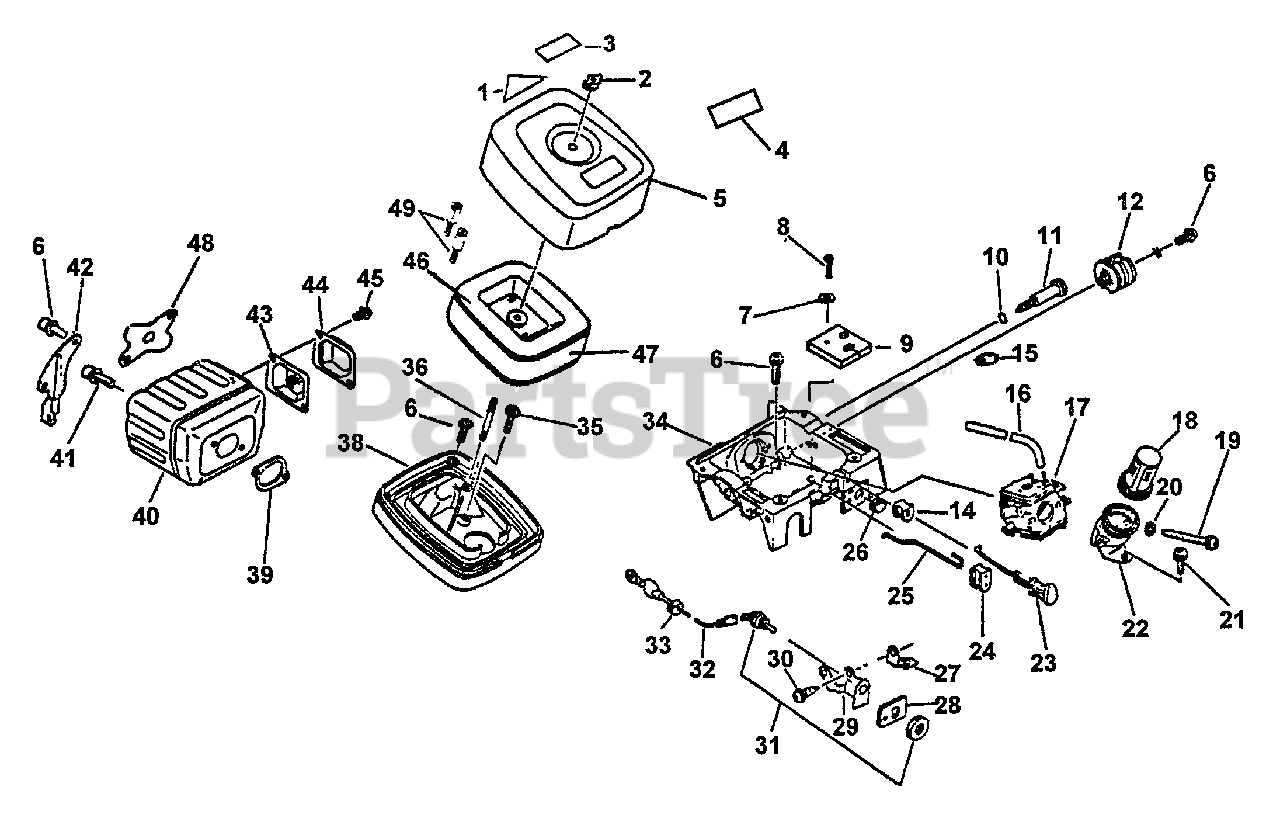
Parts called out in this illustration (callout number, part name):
2	NUT
3	LABEL, CAUTION
4	LABEL, MODEL
5	COVER, AIR FILTER
6	BOLT 5×14
8	PIN, COTTER 3×18
9	PAD, FOAM
10	O-RING 7
11	SCREW, IDLE ADJUST - GRAY
14	GROMMET
16	PIPE, IMPULSE
17	CARBURETOR - HDA-85
18	SCREEN, FILTER
19	SCREW 5×53
20	WASHER, FLAT 5.5×10×0.8
21	SCREW 5×14
23	ROD, CHOKE
24	GROMMET, THROTTLE ROD
25	ROD, THROTTLE
27	PLATE, GROUND
28	LABEL - SWITCH
29	BRACKET, SWITCH
30	SCREW 5×10
31	SWITCH, ON-OFF
32	LEAD - GROUND
34	CASE, CARBURETOR
35	BOLT 5×25
38	CASE, AIR FILTER
39	GASKET, EXHAUST
40	MUFFLER
41	BOLT 5×20
42	BRACKET, MUFFLER
43	SCREEN, SPARK ARRESTER
44	COVER, MUFFLER
45	BOLT 4×10
46	FILTER, AIR
47	FILTER, AIR
48	COVER, MUFFLER
49	BOLT - 5×16
